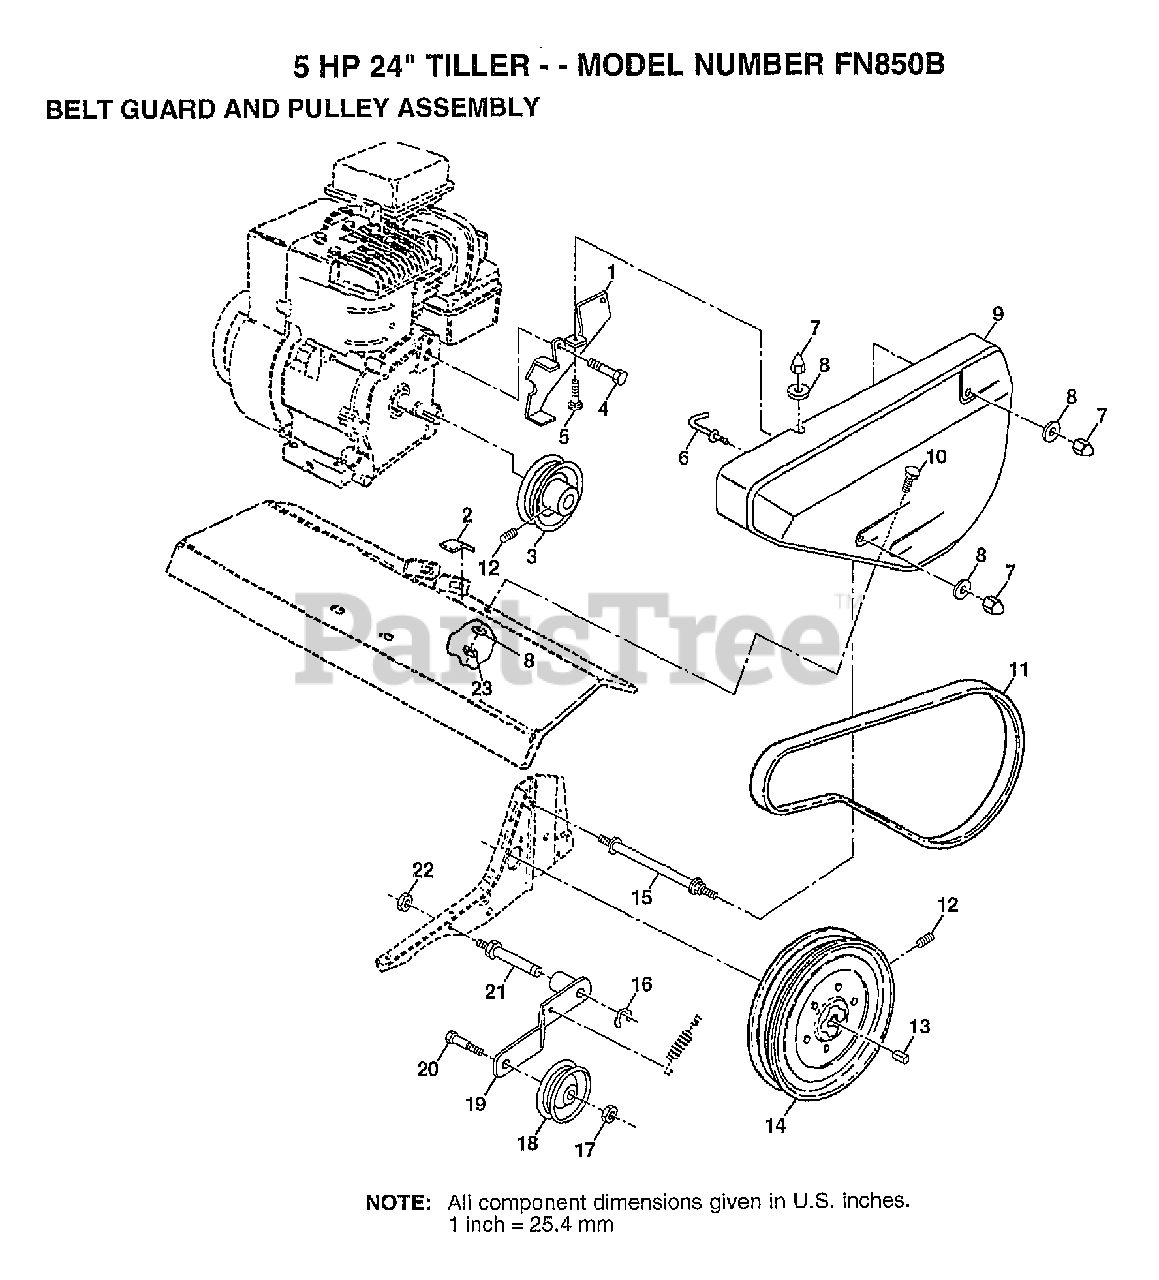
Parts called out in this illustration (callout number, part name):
2	PAD IDLER TI
3	ENGINE PULLEY
5	BOLT
7	NUT-CAP TI
8	WASHER
9	"GUARD, BELT"
10	BOLT T
11	V BELT STD
12	SET SCREW
13	KEY T
14	TRANS SHEAVE RT
15	BOLT TI
16	KLIP RING TI
17	NUT
19	IDLER ARM TI
21	SHAFT IDLER TI
22	JAM NUT TI
23	NUT
